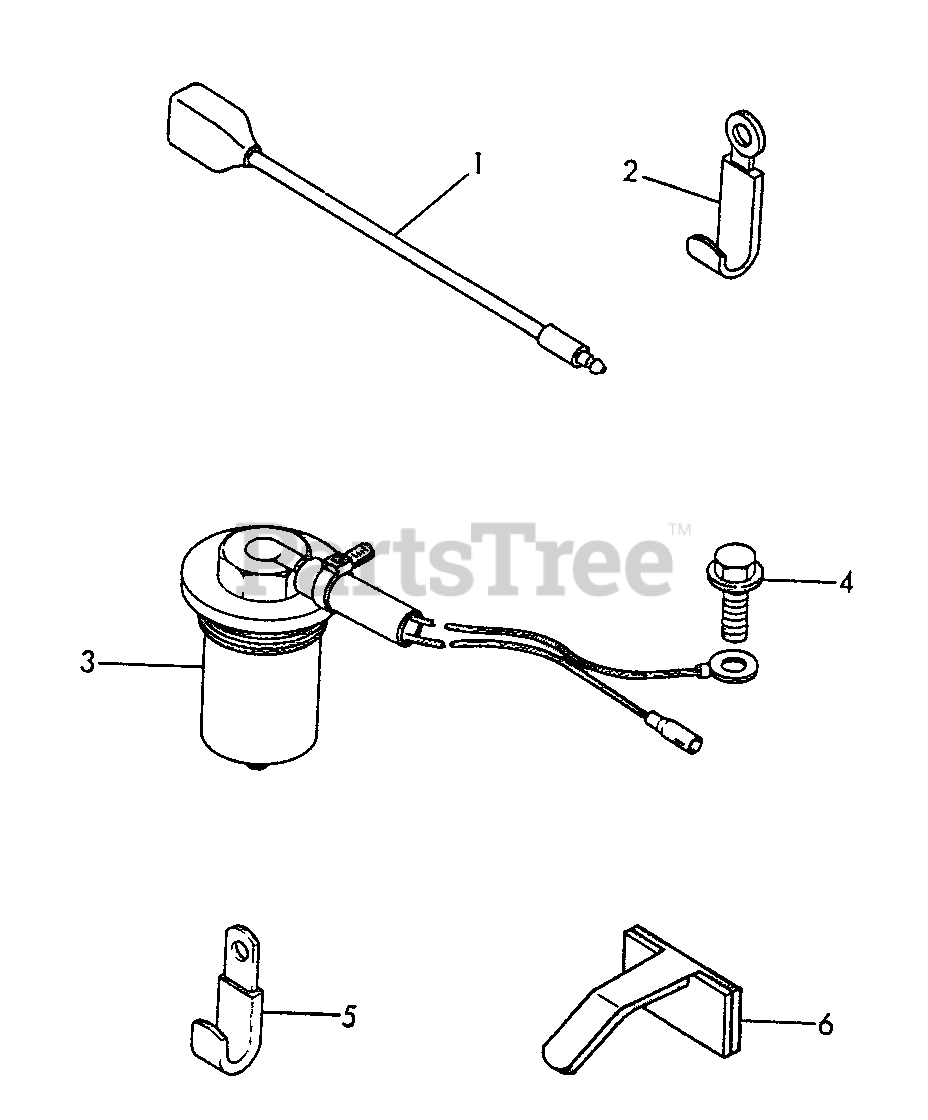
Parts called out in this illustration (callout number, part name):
2	CLAMP
3	SENSOR, OIL LEVEL
4	BOLT - 6X12
5	CLAMP
6	CLAMP
